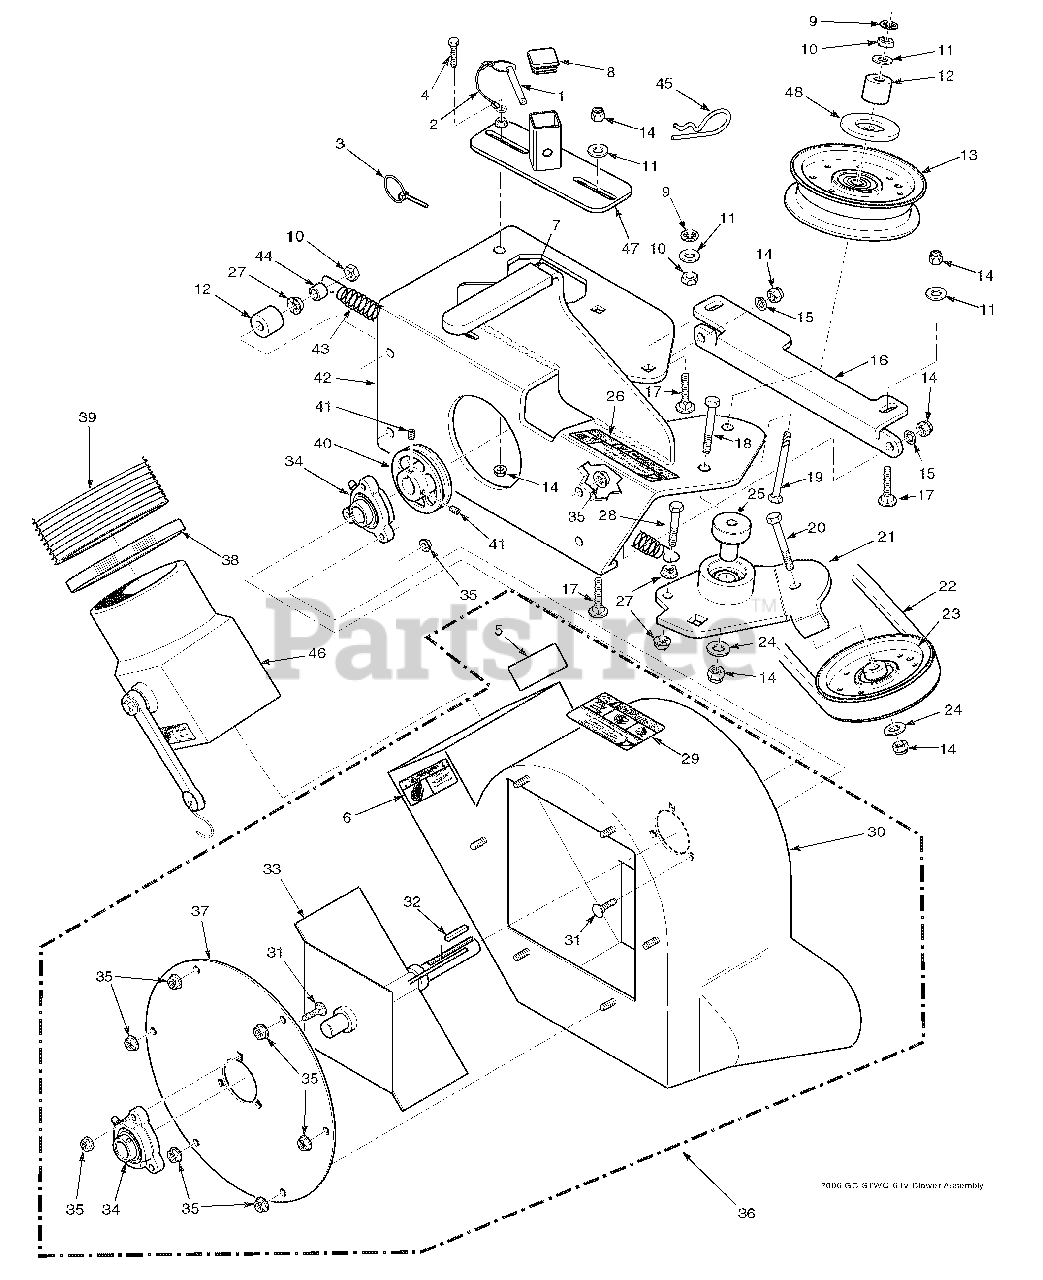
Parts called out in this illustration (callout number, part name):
1	Pin, Ring 2-1/4" Long
2	Lanyard, Deck Height Pin
3	Quick Pin, 5/16" Dia.
4	Bolt, Hex Head 3/8-16 x 1-3/4"
5	Decal, Blower
6	Decal, Rotating Blower
7	Grip, Blower Lever
8	Cap, Square
9	Nut, Push On 3/8 Thread
10	Lock Nut, 3/8-16
11	Flatwasher, 3/8-.391 x .938 x .105
12	Spacer
13	Pulley, Idler 4" Dia.
14	Nut, Elastic Stop 3/8-16
15	Lockwasher, 3/8-16
16	Plate, Catcher Mounting
17	Bolt, Carr. 3/8-16 x 1-1/2"
18	Bolt, Hex Head 3/8-16 x 2-1/4"
19	Bolt, Hex Head 3/8-16 x 3-1/2"
20	Bolt, Hex Head 3/8-16 x 1-3/4"
21	Idler Arm Assembly
22	Belt, GC-STC
23	Pulley, 3-1/2" O.D., GC-STC
24	Washer, 3/8 Hardened
25	Pivot, Idler
26	Decal, Belt Cover
27	Nut, Serr. Flange 3/8-16
28	Bolt, Hex Head 3/8-16 x 1-1/2 Gr. 8
29	Decal, Danger
30	Blower Housing Weldment
31	Bolt, Carr. 5/16-18 x 3/4" Gr. 5
32	Key, 1/4 x 1/4 x 1-1/2"
33	Fan Weldment
34	Bearing Assembly
35	Nut, Serr. Flange 5/16-18
36	Blower Housing Assembly, GC-STT
37	Cover, Blower Housing
38	Clamp, 8-5/8" Max Dia.
39	Hose, 8.00" Dia. x 60.50" Long
40	Pulley, 4-3/4" O.D. - 1" Bore
41	Set Screw, 5/16-18 x 3/8"
42	Frame, Blower Mount
43	Spring, Main Drive
44	Spacer
45	Hair Pin Cotter, .177 x 3-1/4"
46	Adapter w/Strap
47	Receiver Weldment, Mounting Post
48	Dust Shield
